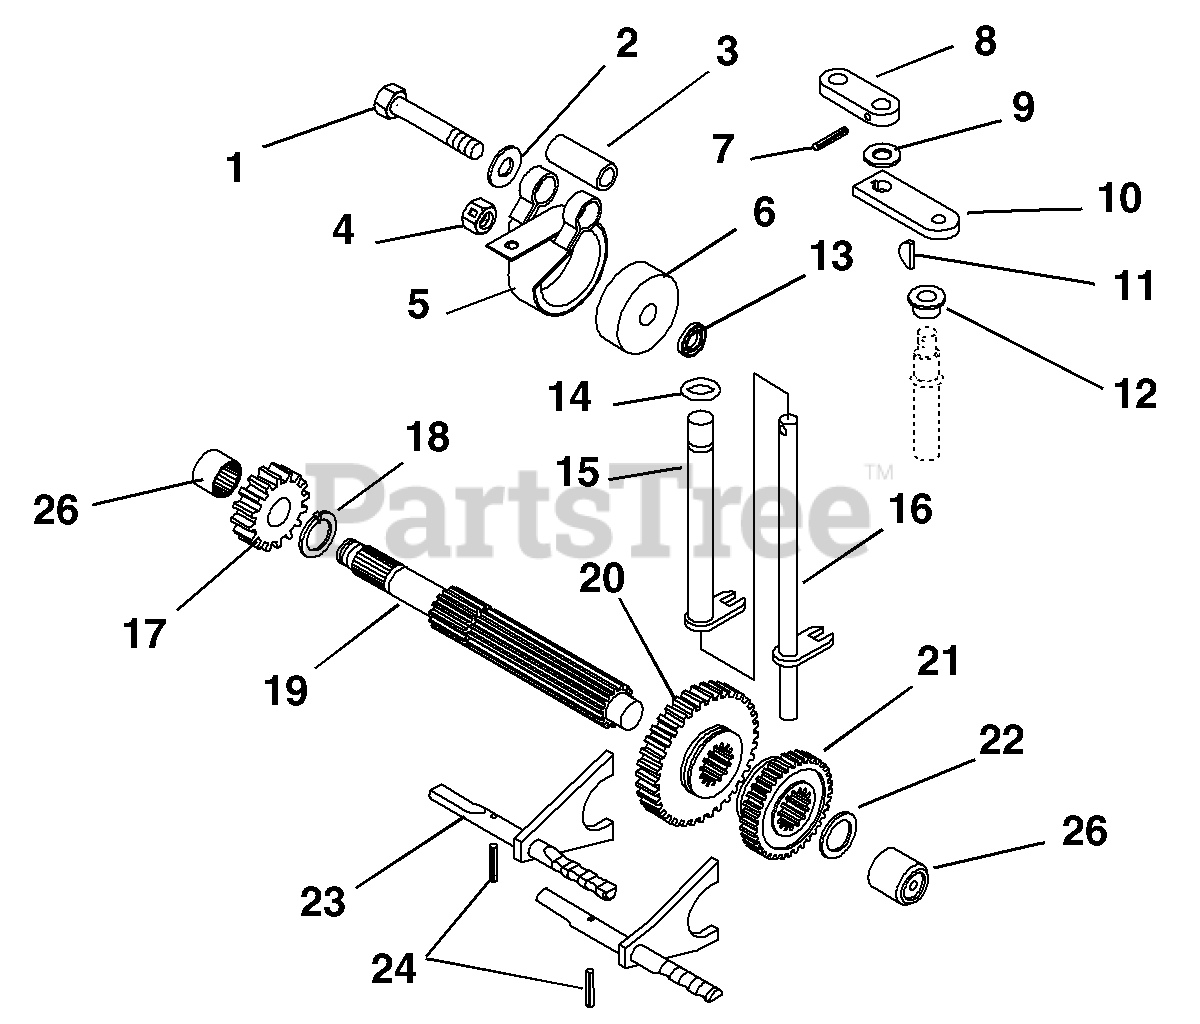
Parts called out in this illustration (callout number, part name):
1	Bolt-Hex .50-13 x 2.75 Grade 5
2	Washer-Flat-Steel .53 x 1.06 x .095
3	Bushing-Sleeve Steel .55 x .75 x 2.06
4	Nut-Locking-Center .62-11
5	Assembly, Brake Band
6	Drum-Brake
7	Pin-Roll .19 x 1.00
8	Arm, Shifter
9	Washer-Felt .44 x 1.00 x .031
10	Arm, Shifter
11	Key-Woodruff Hard .13 x .38 Hard
12	Bushing-Flange Bronze .76 x 1.13 x .75
13	Seal .75 x 1.25 x .136
14	O-Ring .625 x .75 x .062
15	Weldment, 1st and 3rd Shifter
16	Weldment, 2nd and 4th Shifter
17	Gear, 8 Diametral Pitch 16 Teeth x .85
18	Ring-Retaining External .92 x .125
19	Shaft, Slide Gear
20	Gear, Sliding 10 Diametral Pitch 36 Teeth x .59
21	Gear, Sliding 10 Diametral Pitch 30 Teeth x .59
22	Washer-Hardened-Thrust .76 x 1.25 x .094
23	Weldment, Rail Shift Fork 1 and 3
24	Pin-Roll .25 x .75
25	Weldment, Rail Shift Fork 2 and 4
26	Bearing-Needle .75 x 1.00 x .75
